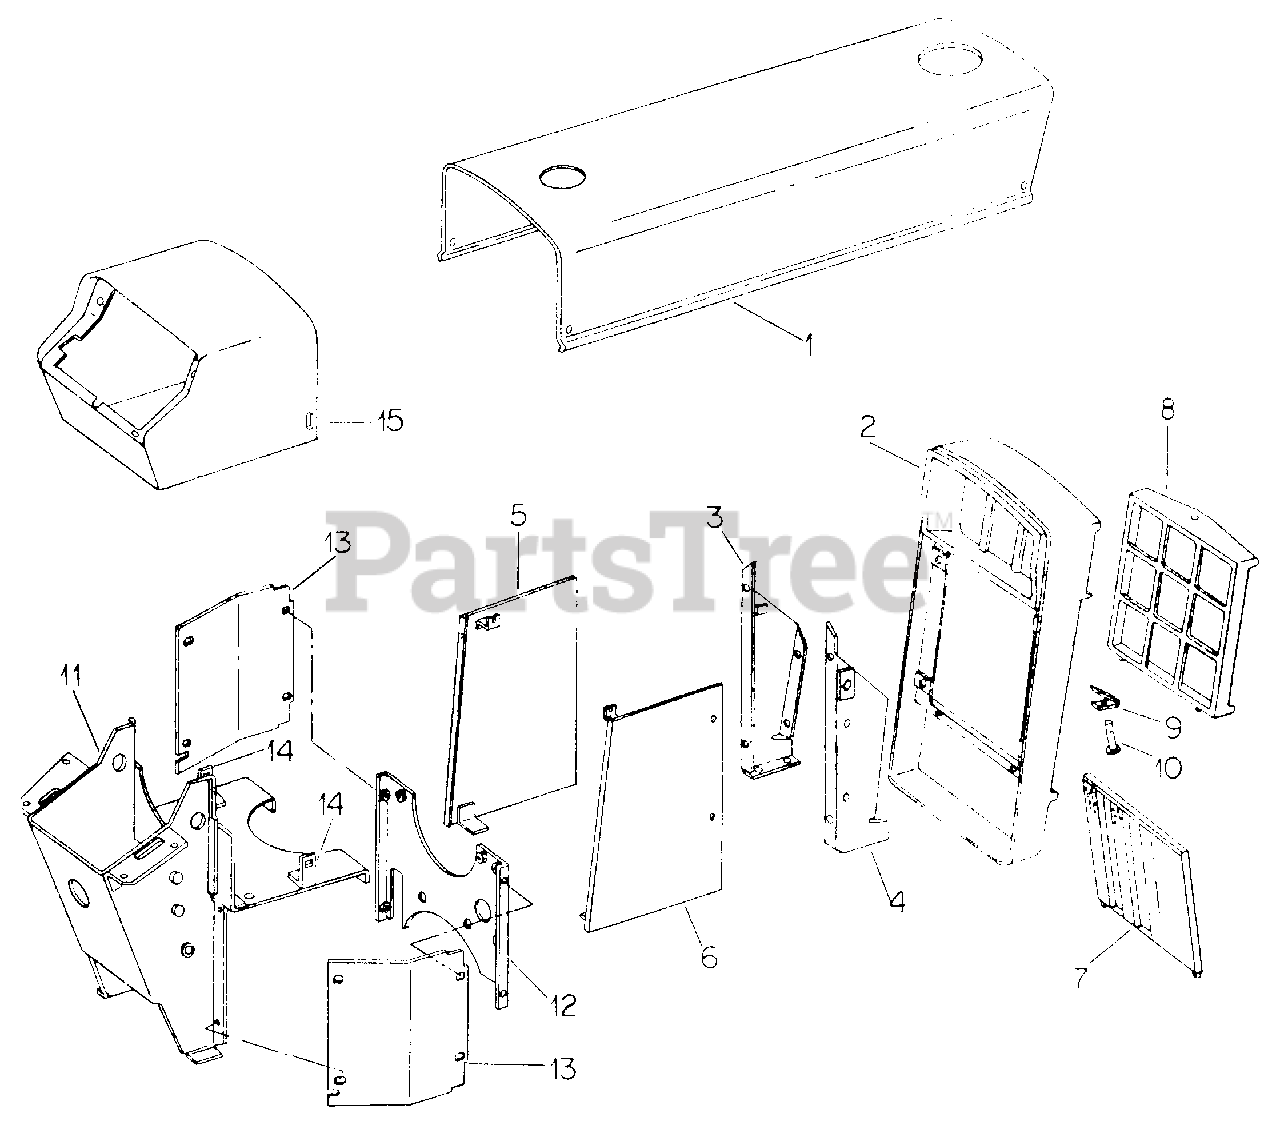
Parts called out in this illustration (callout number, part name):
2	HOUSING, GRILLE
3	SUPPORT ASSY, GRILLE HOUSING & RADIATOR LH
4	SUPPORT ASSY, GRILLE HOUSING & RADIATOR RH
5	PANEL ASSY, GRILLE SIDE LH
6	PANEL ASSY, GRILLE SIDE RH
7	SCREEN ASSY, GRILLE
8	GRILL, INSERT
9	SPRING, LATCH
11	PEDESTAL ASSY
12	SECTION ASSY, PEDESTAL FRONT SHEET
13	SUPPORT, SIDE - PANEL
14	BRACKET ASSY, HOOD HOLD DOWN
15	COWL, INSTRUMENT PANEL
